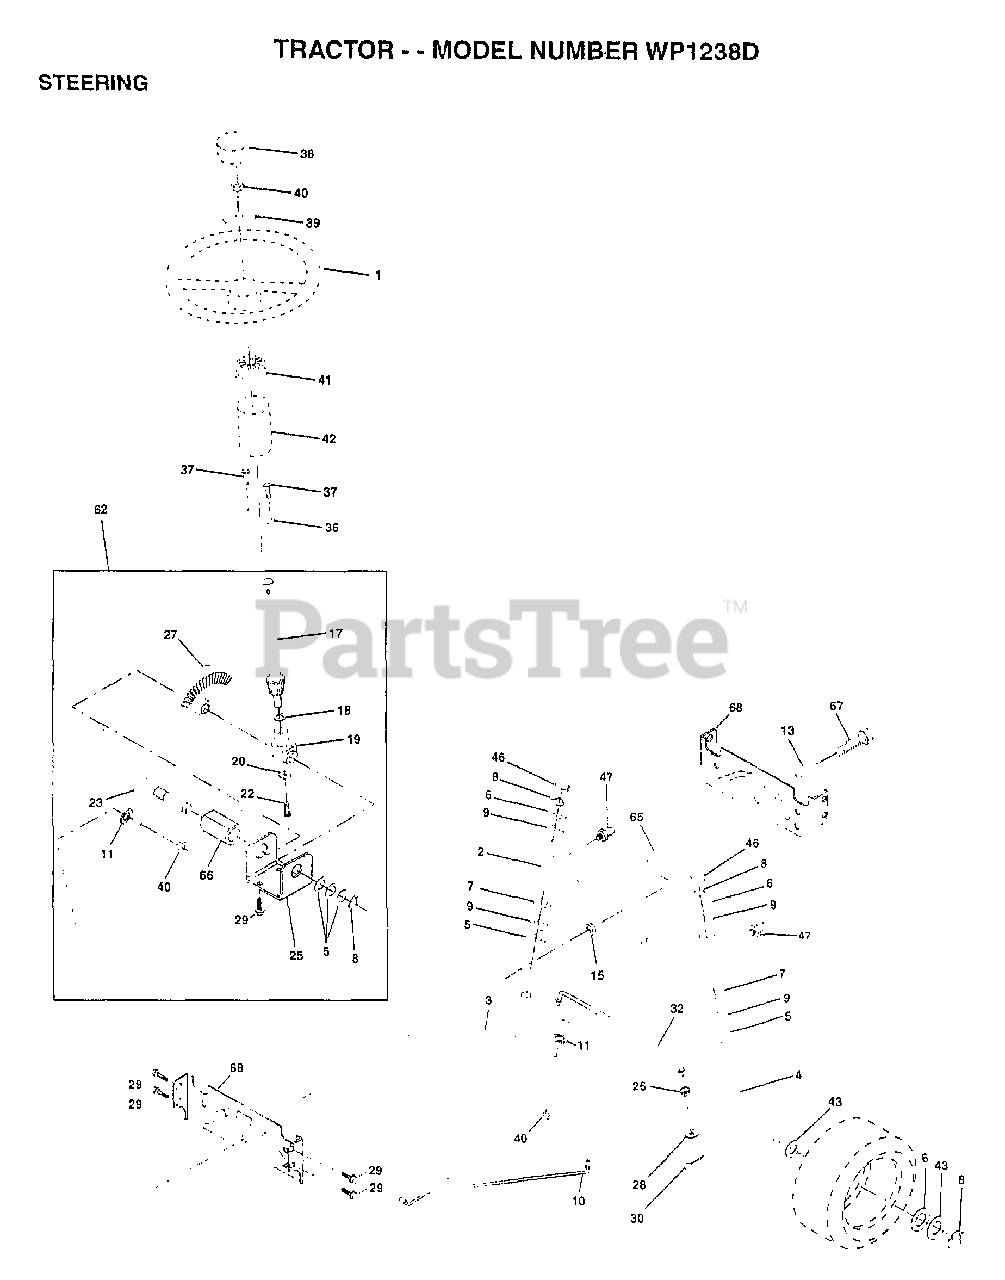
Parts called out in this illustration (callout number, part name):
2	AXLE ASM
3	SPINDLE.ASM.LH
4	"SPINDLE ASM,RH"
5	WASHER .T
6	WASHER
7	WASHER
8	RING
9	COL. SRTG. BEAR.
10	DRAGLINK-STAMPED
11	LOCKWASHER
13	BEARING AXLE
15	"NUT-LOC,FLANGE LT"
17	SHAFT ASSM STEERN
18	THRUST WASHER
19	SUPPORT.SHAFT
22	SCREW HEX SOC1/4-
25	BRKT-STEERING
26	BUSHING.DRAGLINK
27	GEAR SECTOR
28	WASHER
29	SCREW
30	COTTER PIN
32	TIE ROD
36	BUSHING.STEERING
37	"SCREW-TT,10-32 FL"
38	ST WHL INSERT CAP
39	WASHER T
40	GRIPCO NUT
41	ADAPTER-WHEEL LT
42	"TUBE, STR SHAFT"
43	WASHER
46	CAP
47	ZERK M
62	STEERING ASM KIT
65	SPACER AXLE
66	"BEARING-ARM,PITMA"
67	BOLT
68	BRACE AXLE
